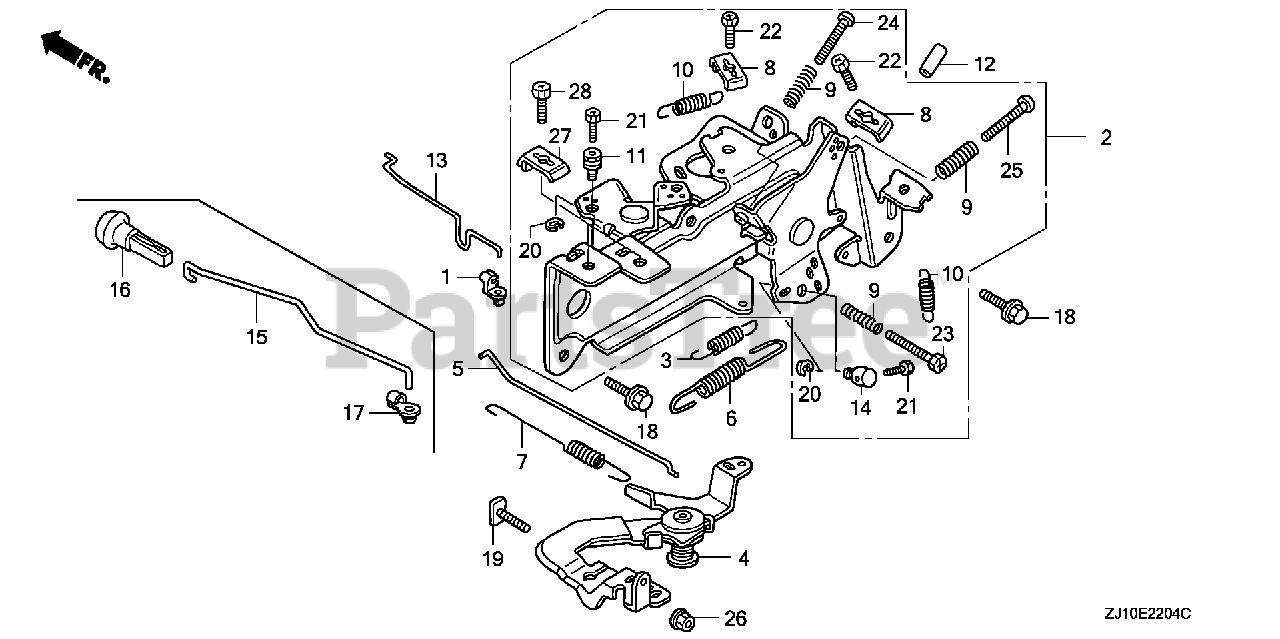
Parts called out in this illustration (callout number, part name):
1	JOINT, ROD
2	CONTROL ASSY. (AUTO THROTTLE)
3	SPRING, STARTER
4	ARM, GOVERNOR
5	ROD, GOVERNOR
6	SPRING, GOVERNOR (MANUAL)
7	SPRING, THROTTLE RETURN
9	SPRING, CONTROL ADJUSTING
13	ROD, CHOKE CONTROL
15	ROD, CHOKE KNOB
16	KNOB, CHOKE
17	BUSH, LINKAGE
18	BOLT, FLANGE (6X14) (CT200)
19	BOLT, GOVERNOR ARM
23	BOLT, RECESSED (5X25)
25	SCREW, PAN (5X35)
26	NUT, FLANGE (6MM)
